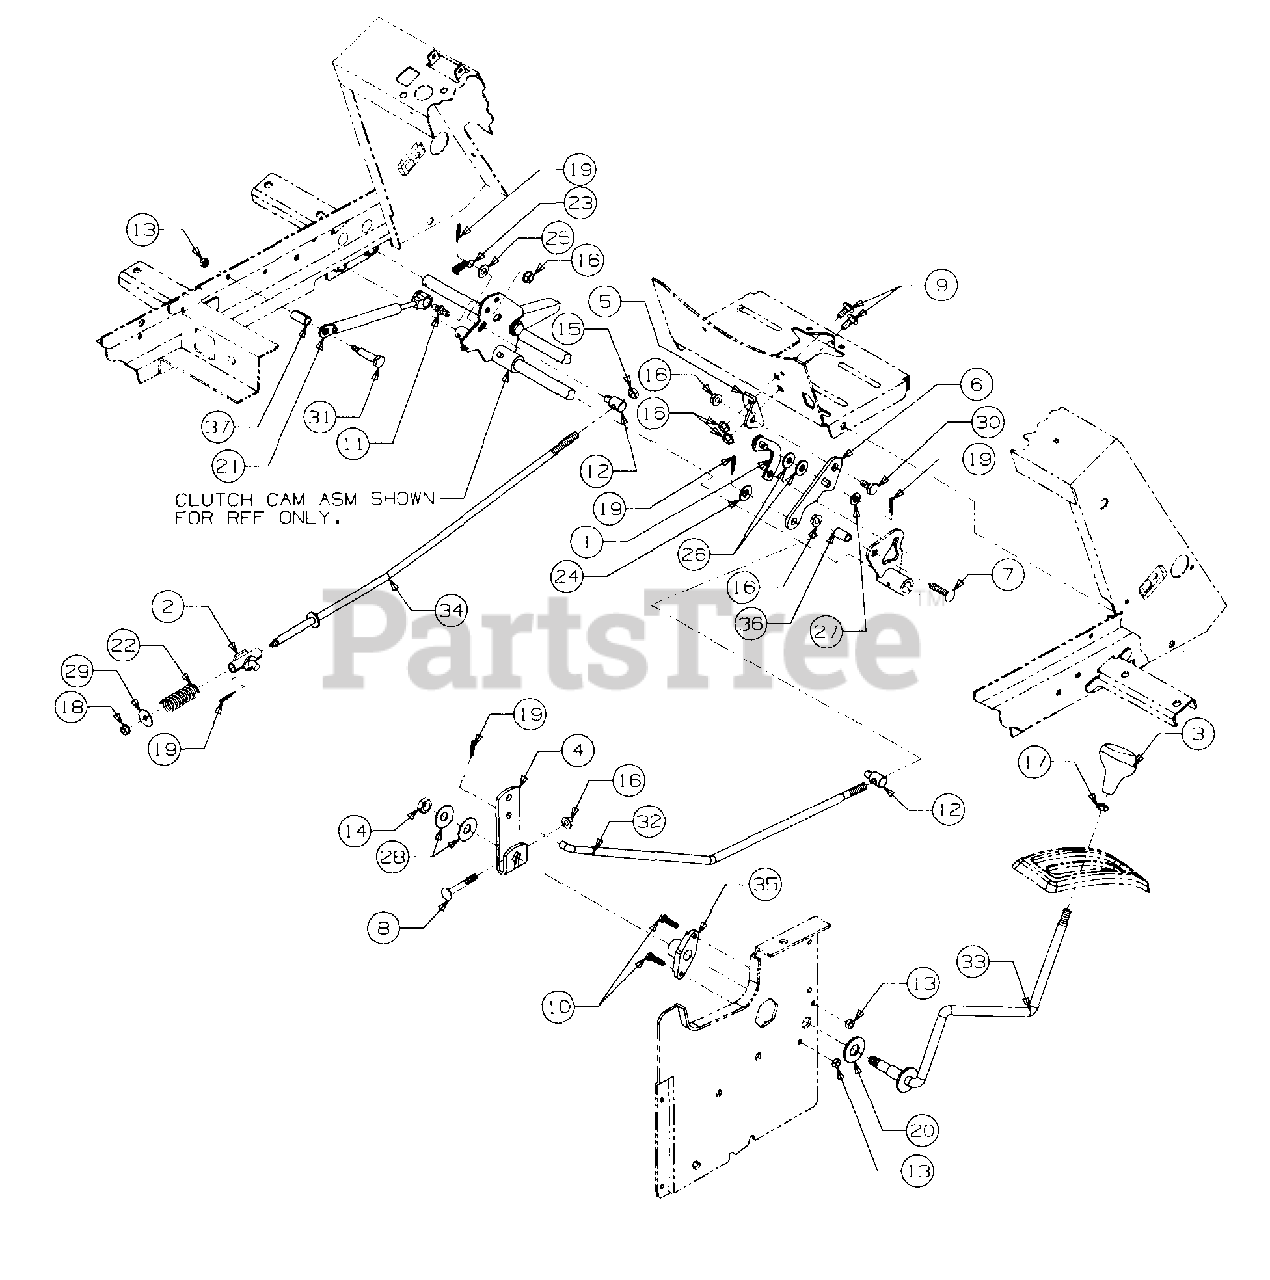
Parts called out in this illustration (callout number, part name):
1	Bracket Assy, Cruise Return
2	Pivot Assy, Sleeve
3	Knob, Shifter
4	Bracket, Gear Shift
7	Bolt, Carriage, 5/16-18 x 1.50 Lg
8	Bolt, Carriage, 5/16-18 x 2.25 Lg GR5
9	Bolt, Carriage, 5/16-18 x .75 Lg
10	Screw, Hex Cap, 1/4-20 x 1.0 Lg
11	Screw, Ball, 5/16-18
12	Ferrule, Adjustment
13	Nut, Hex Sems, 1/4-20
14	Nut, Hex Jam Lock, 1/2-20
15	Nut, Hex Jam, 3/8-24 GR5
16	Nut, Hex Flange Top Lock, 5/16-18
17	Nut, Hex Jam, 3/8-16 GR5
18	Nut, Hex Flange Lock, 1/4-20
19	Pin, Internal Cotter, 5/16 Dia x 1.12 Lg
20	Washer, Friction
21	Cylinder, Damper
22	Spring, Compression, .63 ID x 2.0 Lg
23	Spring, Extension, .38 OD x 1.44 Lg
24	Washer, Bell, .380 x .88 x .062 Thk
25	Washer, Flat, .406 x .75 x .063 Thk
26	Washer, Flat, .375 x .870 x .090 Thk
27	Washer, Flat, 5/16
28	Washer, Bell
29	Washer, Flat, .265 x 1.0 x .030 Thk Hdn
30	Bolt, Shoulder, .437 Dia x .180 Lg
31	Bolt, Shoulder, .374 Dia x 1.375 Lg
32	Rod, Hydro Stop
33	Lever, Cruise Control
34	Rod, Hydro Adjustment
35	Bushing, Control Lever
36	Spacer, .3776 ID x .500 OD x .830 Lg
37	Spacer, Split Tubing, .375 ID x .520 OD x 1.04 Lg
